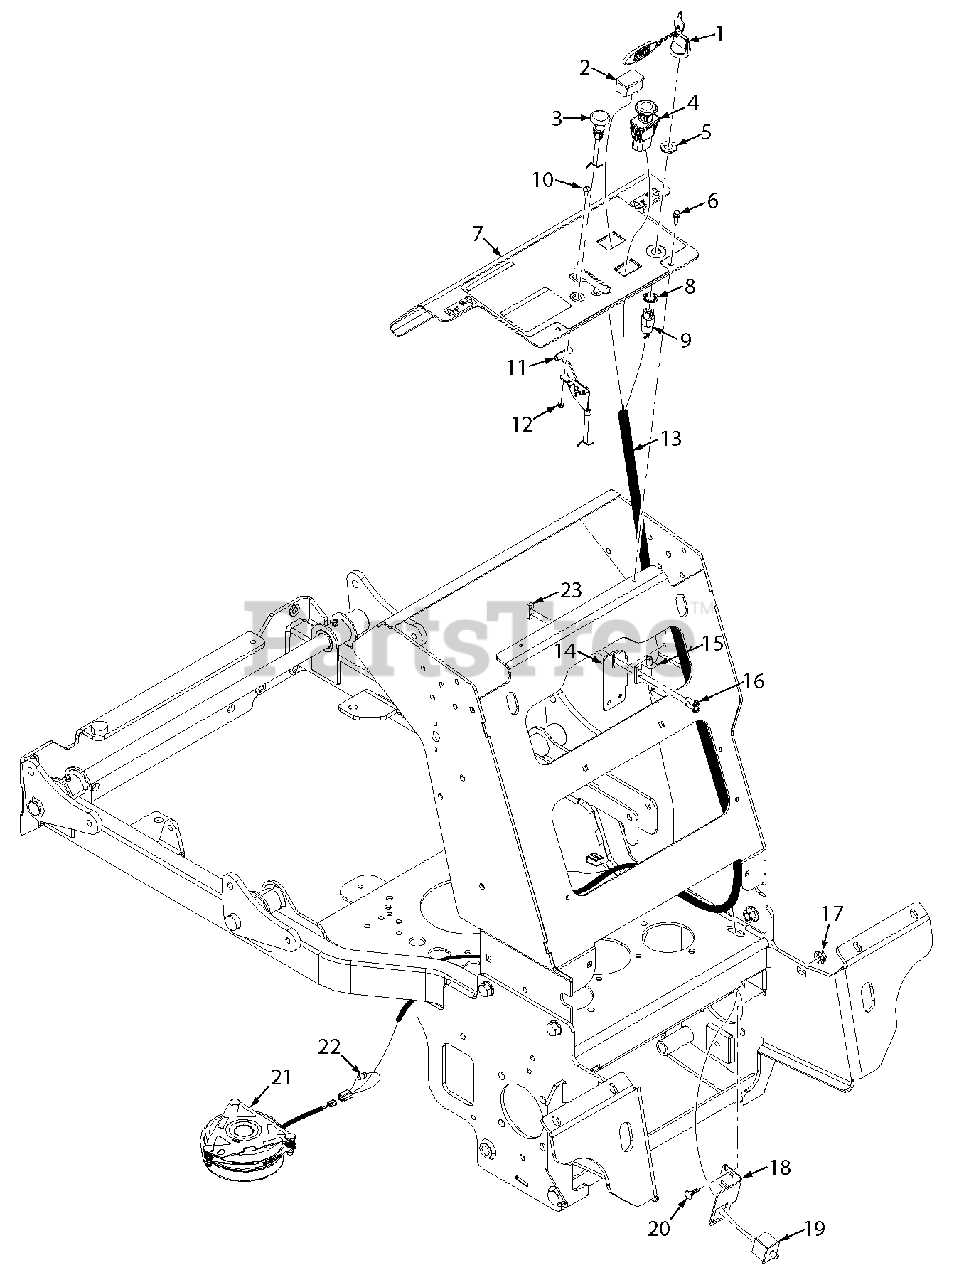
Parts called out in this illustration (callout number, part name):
1	Key Assy., w/Fob
2	Hourmeter
3	Choke Control
4	Switch, PTO
5	Nut, Special 5/8-32
6	Screw, 1/4-20 x 3/4" Taptite
7	Instrument Panel w/Decal - SVRII36
8	Lockwasher, 5/8" Internal Tooth
9	Switch, Key
10	Bolt, Carriage #10-24 x 1/2"
11	Throttle Cable
12	Nut, Elastic Stop #10-24
13	Wire Harness, SVRII Recoil Start
14	Bracket, Neutral Switch
15	Switch, Interlock
16	Screw, #10-32 x 3/4" Taptite
17	Nut, Serrated Flange 1/4-20
18	Switch Bracket, Operator Presence
19	Switch, Double Pole - N.O. / N.O.
20	Bolt, Carriage 1/4-20 x 3/4"
21	Clutch w/Tag GT2.5-FE02
22	Diode, 600V - 6A
23	Plate, Threaded
